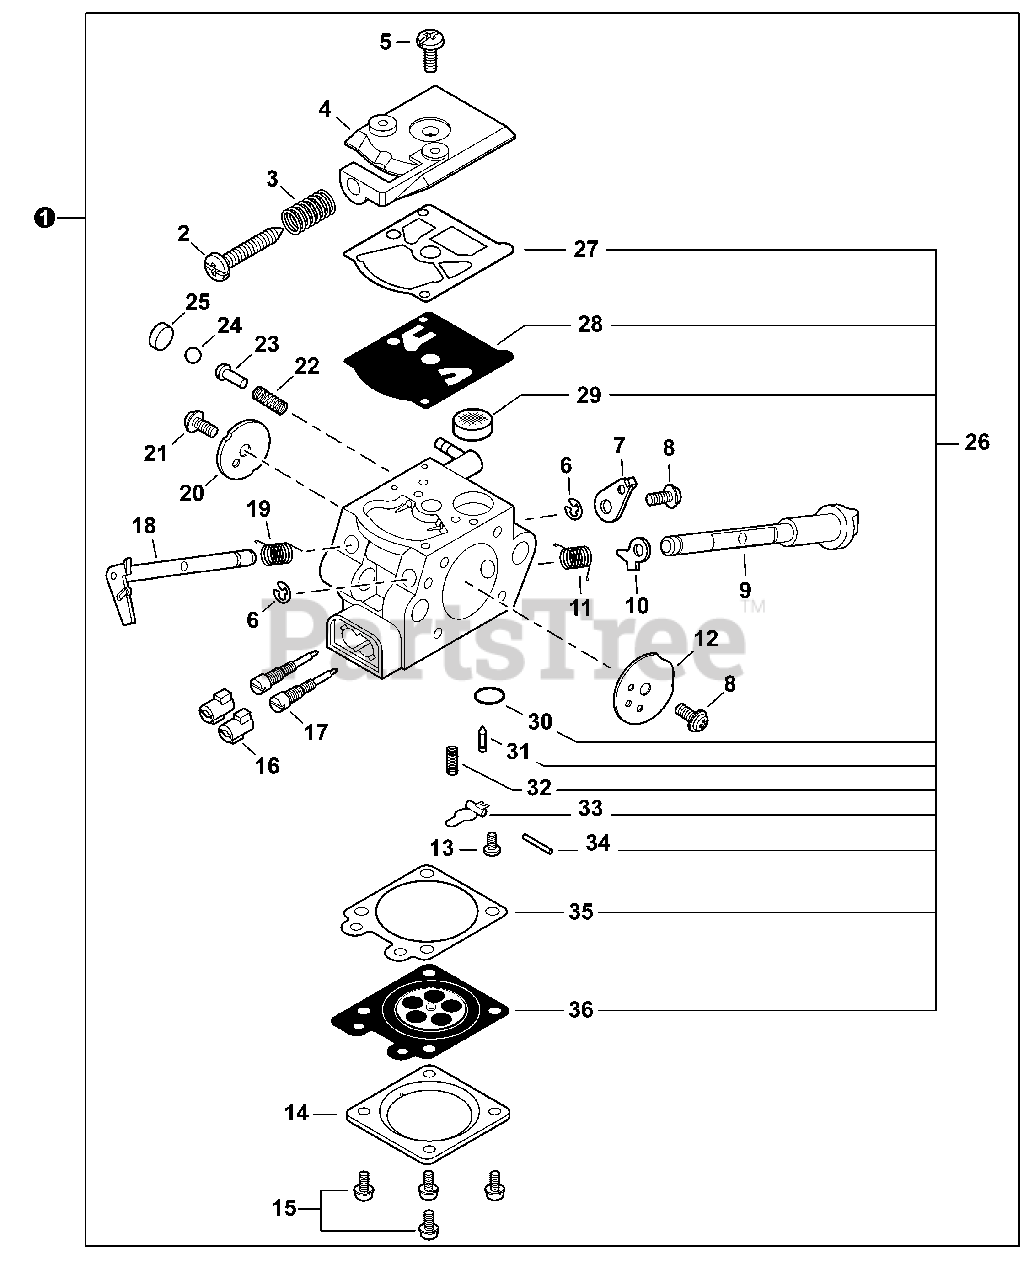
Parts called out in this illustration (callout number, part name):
1	CARBURETOR WT-1072
2	SCREW, IDLE ADJUST
3	SPRING, IDLE ADJUST
4	COVER, FUEL PUMP
7	LEVER, THROTTLE
9	SHAFT ASSY, CHOKE
10	LEVER, FAST IDLE
12	VALVE, CHOKE
13	SCREW, METERING LEVER PIN
14	COVER, METERING DIAPHRAGM
16	CAP, LIMITER
17	NEEDLE, MIXTURE
18	SHAFT ASSY, THROTTLE
19	SPRING, THROTTLE RETURN
20	VALVE, THROTTLE
22	SPRING, START VALVE
23	PISTON ASSY
26	REPAIR KIT, CARBURETOR
27	GASKET, PUMP
28	DIAPHRAGM, PUMP
29	SCREEN, INLET
30	PLUG, WELCH
31	VALVE, INLET NEEDLE
32	SPRING, METERING LEVER
33	LEVER, METERING
34	PIN, METERING LEVER
35	GASKET, METERING DIAPHRAGM
36	DIAPHRAGM, METERING
